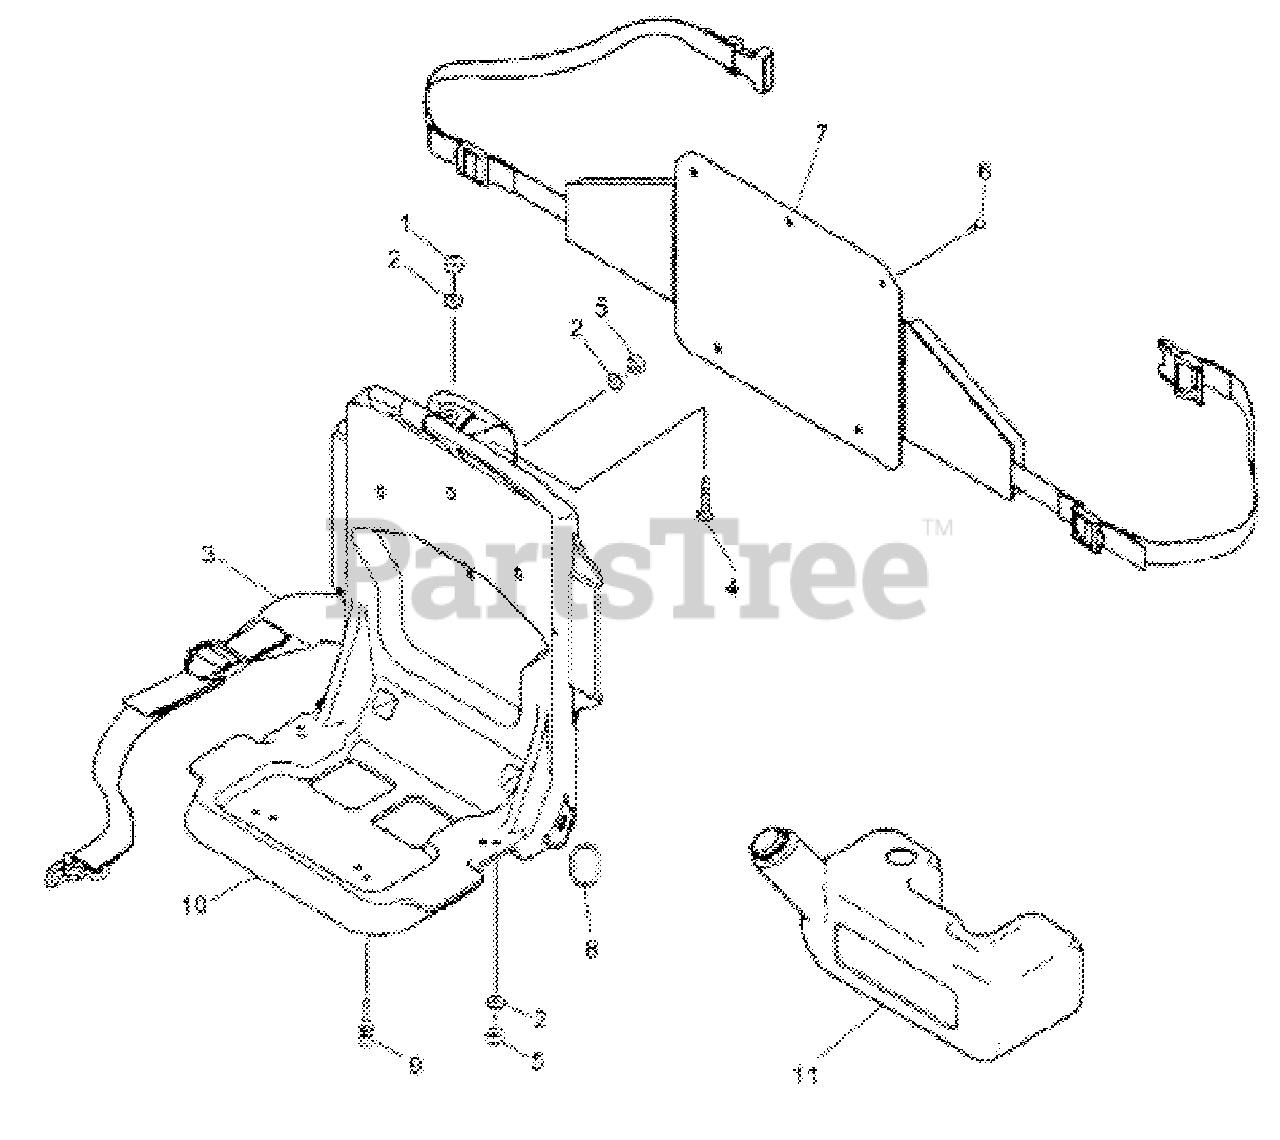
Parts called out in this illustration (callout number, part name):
1	Flange Nylon Nut
2	Washer
3	Shoulder Band
4	Truss Screw
6	Clip
7	Knapsack Pad
10	Knapsack Frame
11	Fuel Tank
